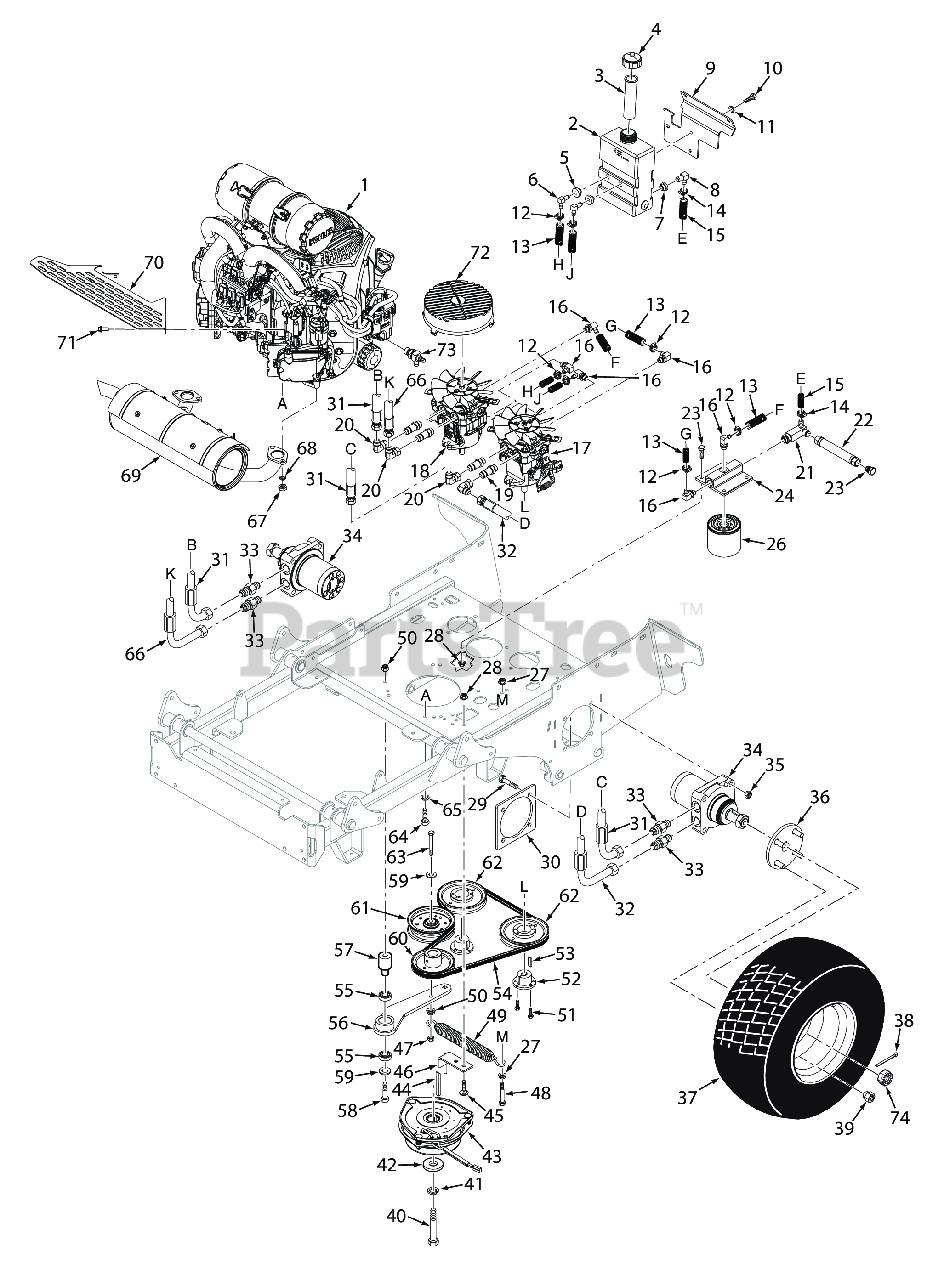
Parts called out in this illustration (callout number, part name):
1	Engine, 22 HP Kawasaki FX
1	Engine, 23hp Kawasaki FX730V
1	Engine, 25 HP Kohler EFI
1	Engine, 25hp Kawasaki FX801V
1	Engine, 29 HP Kohler EFI
2	Hydro Tank Assy., SVRII
3	Insert, Filler Neck
4	CAP, HYDRAULIC TANK
5	Bushing, 0.56" Dia. Viton
6	Elbow, 90 Degree, 9/16-18 JIC x 9/16 O-Ring
7	Bushing, 0.78" Dia. Viton
8	Fitting, 90 Degree - 1/2" Hose
9	Bracket, Hydro Tank Mounting
10	BOLT, SERRATED FLANGE HEX HEAD 5/16-18 X 3/4"
11	Lockwasher, 5/16 (.317 x .586 x .078) Helical Spring
12	Clamp, .69" Max. / .25" Min. Dia.
13	Hose, 3/8" ID - 10-1/4" Long (Order By The Inch)
14	Clamp, Cable 3/4" I.D.
15	Hose Assembly, 1/2" ID (Oil Reservoir to Filter Base)
16	Elbow, 90 Degree - 9/16" O-Ring x 3/8" Hose
17	Pump, LH - SVRII
18	Pump, RH - SVRII
19	Union, O-Ring to JIC
20	Elbow, 1/2 JIC Female to 1/2 JIC Male
21	Tee, 3/4" O-Ring
22	Drain, Hose Assembly
23	Plug, JIC 3/4-16 UNF
24	Filter Head Assembly
25	BOLT, SERRATED FLANGE HEX HEAD 5/16-18 X 3/4"
26	OIL FILTER, SPECIAL
27	NUT, 3/8-16 SERRATED FLANGE HEX HEAD
28	Nut, Serrated Flange 5/16-18 (Right Front Engine Mounting, Briggs and Kohler Only)
29	Bolt, Hex Hd. 1/2-13 x 2-1/2" (lower)
30	Plate Weldment, Motor Backing
31	Hose Assy., 27-1/2"
32	Hose Assy., 15-1/4"
33	TUBE UNION, 3/4-16 JIC TO 7/8-14 "O" RING
34	Wheel Motor, SVRII
35	Locknut, Hex 1/2-13 Center Lock
36	WHEEL HUB ASSY, SVRII
36	Bolt, Serr. Flange 1/2-20 x 4.563"
37	Wheel Assembly, 24 x 12-12 (SPZ61)
37	Tire, 24 x 12-12 (SPZ61)
37	(52") Rim 481851 (61") Rim w/Stem
38	Pin, Cotter 9/16" x 1-1/2"
39	Wheel Nut, 1/2-20 x 13/16
40	Bolt, Hex Head 7/16-20 x 2-1/4" w/Patch (Kawasaki)
41	Lockwasher, 7/16� Spring
42	Flatwasher, 7/16-.469 x 1.75 x .25 (48, 52)
43	Clutch w/Tag GT2.5-FE02 (48 / 52)
44	Key, 1/4 x 1/4 x 3-1/2"
45	Bolt, 5/16-18 x .75 RHSN Carriage
46	ANTI-ROTATION WLMT, SVRII
47	Bolt, Hex Head 3/8-16 x 1" Ser. Flg.
48	Bolt, Hex Head 3/8-16 x 3" - 52"
49	Spring, Transmission Idler
50	HEX NUT, ELASTIC STOP LOCK, 3/8-16
51	Bolt, Hex Head 1/4-20 x 1" Grade 8 Black
52	Hub, Tapered, 15mm Bore
53	KEY, 5 MM X 5 MM X 25 MM
54	Belt, Pump Drive (48 & 52)
55	BEARINGS, BALL, NEUTRAL RETURN
56	WHEEL HUB ASSY, SVRII
57	Pivot, Idler
58	Capscrew, Hex Head 3/8-16 x 3.25"
59	Flatwasher, 3/8 (.391 x .938 x .105 HD) Grade 8
60	Pulley, 4-3/4" OD - 1.125 Bore
61	Pulley, Idler 4-1/2"
62	Pulley, 5.45 OD - Tapered Bore"
63	Bolt, Hex Head 3/8-16 x 2-3/4" Full Thread
64	Bolt, Hex Head 3/8-16 x 1-1/4", Kawasaki FX / FS
64	Bolt, Hex Head Self-Tap 3/8-16 x 1-1/4" (Kohler x3 - 25EFI, Kohler x4 - 29EFI)
64	Bolt, Hex Head 5/16-18 x 1-1/2" (Right Front Engine Mounting, Briggs and Kohler Only)
64	Lockwasher, 5/16" Ext. Tooth (Kohler x1)
64	Nut, Serrated Flange 5/16-18 (Right Front Engine Mounting, Briggs and Kohler Only)
65	Lockwasher, 3/8" Spring, Kawasaki FX / FS
66	Hose Assy., 30"
67	Nut, M8 x 1.25 Hex Special
67	Lock Nut, M8-1.25 -8H (Kohler)
68	Lockwasher, M8 Spring (Kawasaki)
69	Muffler, Kawasaki FX - SVRII
69	Muffler, Kohler CV-EFI - SVRII
69	Muffler, Kawasaki FX801 - SVRII
69	Muffler, Kohler, 29 EFI - SVRII
70	Heatshield, Muffler - Kawasaki FX - SVRII
70	Heatshield, Muffler - Kawasaki FX801 - SVRII
70	Heatshield, Muffler - Kohler 29 EFI - SVRII
71	Bolt, Hex Head M8 - 1.25 x 20
71	BOLT, SERRATED FLANGE HEX HEAD 5/16-18 X 3/4"
71	Flatwasher, 5/16-.344 x .688 x .065 (48V / 52V)
71	Nut, Serrated Flange 5/16-18 (Right Front Engine Mounting, Briggs and Kohler Only)
72	Fan Cover, Pump
73	Oil Drain, M20 Thread (Kawasaki)
73	Extension, Oil Drain 2.3" - Kawasaki
74	Nut, Hex Castle 1.0-20 UNEF
